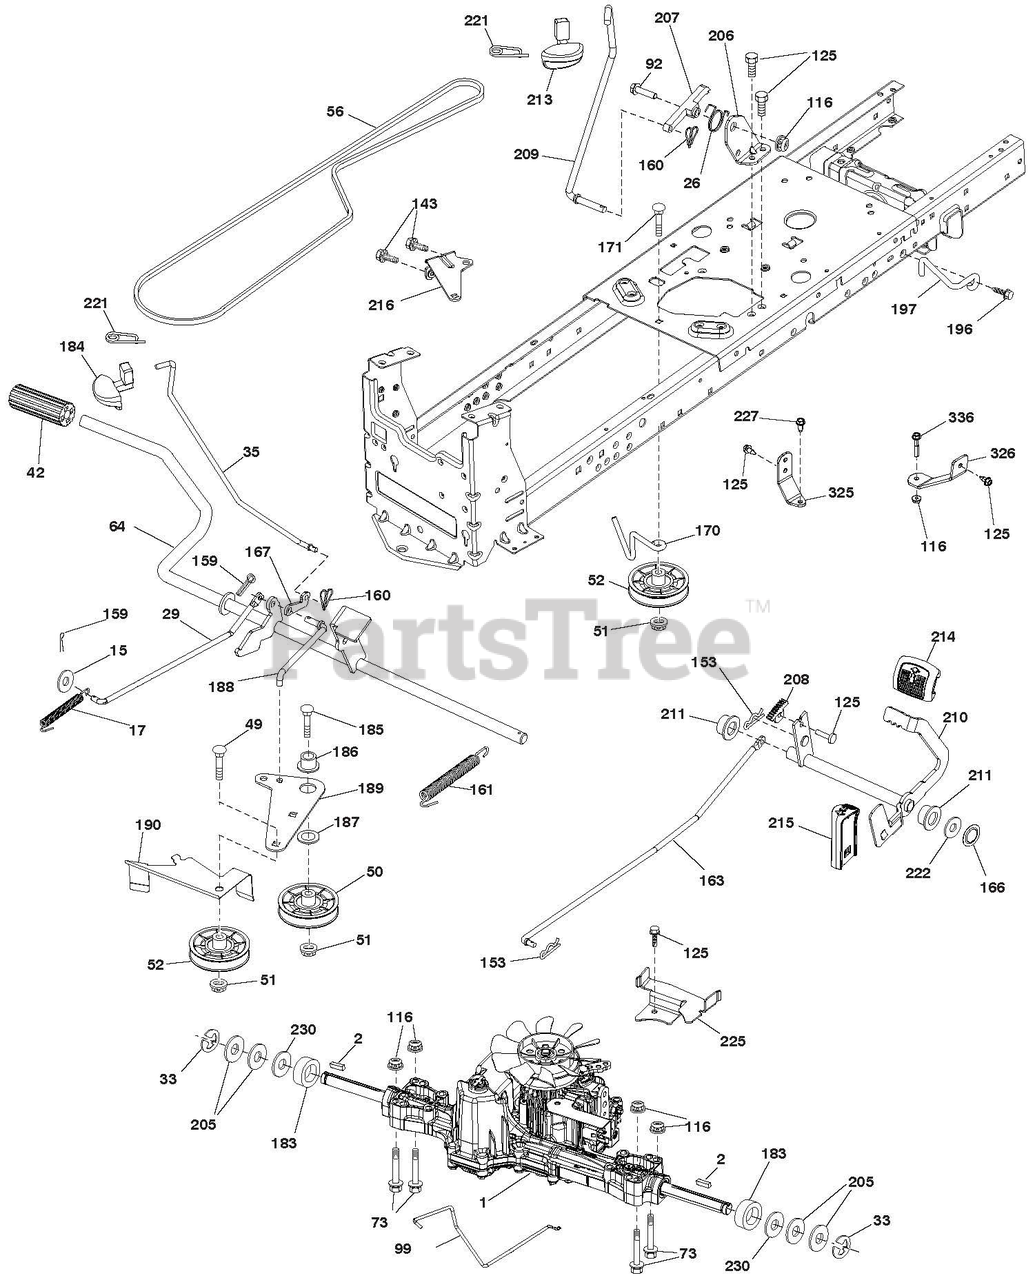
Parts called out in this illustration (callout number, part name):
2	KEY.SQUARE.2.0 X .1845/.1865
15	WASHER.13/32 X 13/16 X 16 GA.
17	SPRING.BRAKE.K46.GREEN
26	SPRING.RETURN.CRUISE
29	ROD.BRAKE.K46
33	E-RING.#5133-75
35	ROD.BRAKE.PARKING.LT.TEX
42	COVER PEDAL BLK ROUND
49	BOLT.RDHD.3/8-16UNCX1-3/4.GR5
50	IDLER.FLAT.910"OFFSET
51	Nut, Hex, Flangelock 3/8-16
52	IDLER.V-GROOVE.910"OFFSET
56	V-BELT.MOWER.92.40.42/K46
64	SHAFT ASM.PEDAL.BRK.CNTRL.PCH
73	BOLT.HEX.FLGHD.5/16-18.GR.5
92	Bolt, Hex Head 5/16-18 x 1-1/4
99	ROD BYPASS
116	Nut, Lock Hex Flange 5/16-18 u
125	SCREW.5/16-18X3/4.SMGML.TAP/BL
143	SCREW.THDROL.5/16-18 X 1/2TYTT
153	RETAINER SPRING
159	PIN.COTTER.1/8 X 3/4.CAD.
160	RETAINER.CLIP(M).DIA.290
161	SPRING.RETURN.CLUTCH.6.75
163	ROD CONTROL
166	NUT PUSH .625
167	LATCH.BRAKE.PARKING
170	KEEPER BELT CENTERSPAN
171	BOLT.RD.HD.SQ.NK.3/8-16UNC X 2
183	SPACER.AXLE.HYDRO/PEERLES
184	HANDLE.PARK.BRAKE
185	BOLT.RDHD.3/8-16UNC X2-3/4 GR5
186	SPACER.RETAINER
187	WASHER.13/32 X 2 X 10 GA.
188	LINK.CLUTCH.GROUND DRIVE
189	BELLCRANK.GROUNDRIVE.NSTG/NSTL
190	KEEPER.BELLCRANK.DRIVE.GROUND
196	SCREW.3/8-16X1.SMGML.TAP/R.BLK
197	LINK CLUTCH ANTI-ROTATION
205	WASHER.25/32 X 1-5/8 X 16GA.
206	BRACKET MOUNT LATCH CRUISE
207	LATCH.CONTROL.CRUISE
208	GEAR SECTOR.CONTROL.CRUISE
209	ROD.CONTROL.CRUISE
210	ROCKER ASM.PEDAL CONTROL.TEXLT
211	BEARING.NYLON.BLK..629 ID.
213	KNOB.CONTROL.CRUISE
214	PAD PEDAL FORWARD
215	PEDAL REVERSE
216	BRACKET.PULLEY.IDLER.WTEX
221	HANDLE.PARK.BRAKE
222	WASHER.21/32X1-1/4.10GA.N/PLTD
225	KEEPER.BELT.TRANSAXLE.K46
227	SCREW 5/16-18 X 3/4
230	WASHER.HARDEN..793 X 1.637X060
325	TORQ. STRAP LH
326	TORQ. STRAP RH
